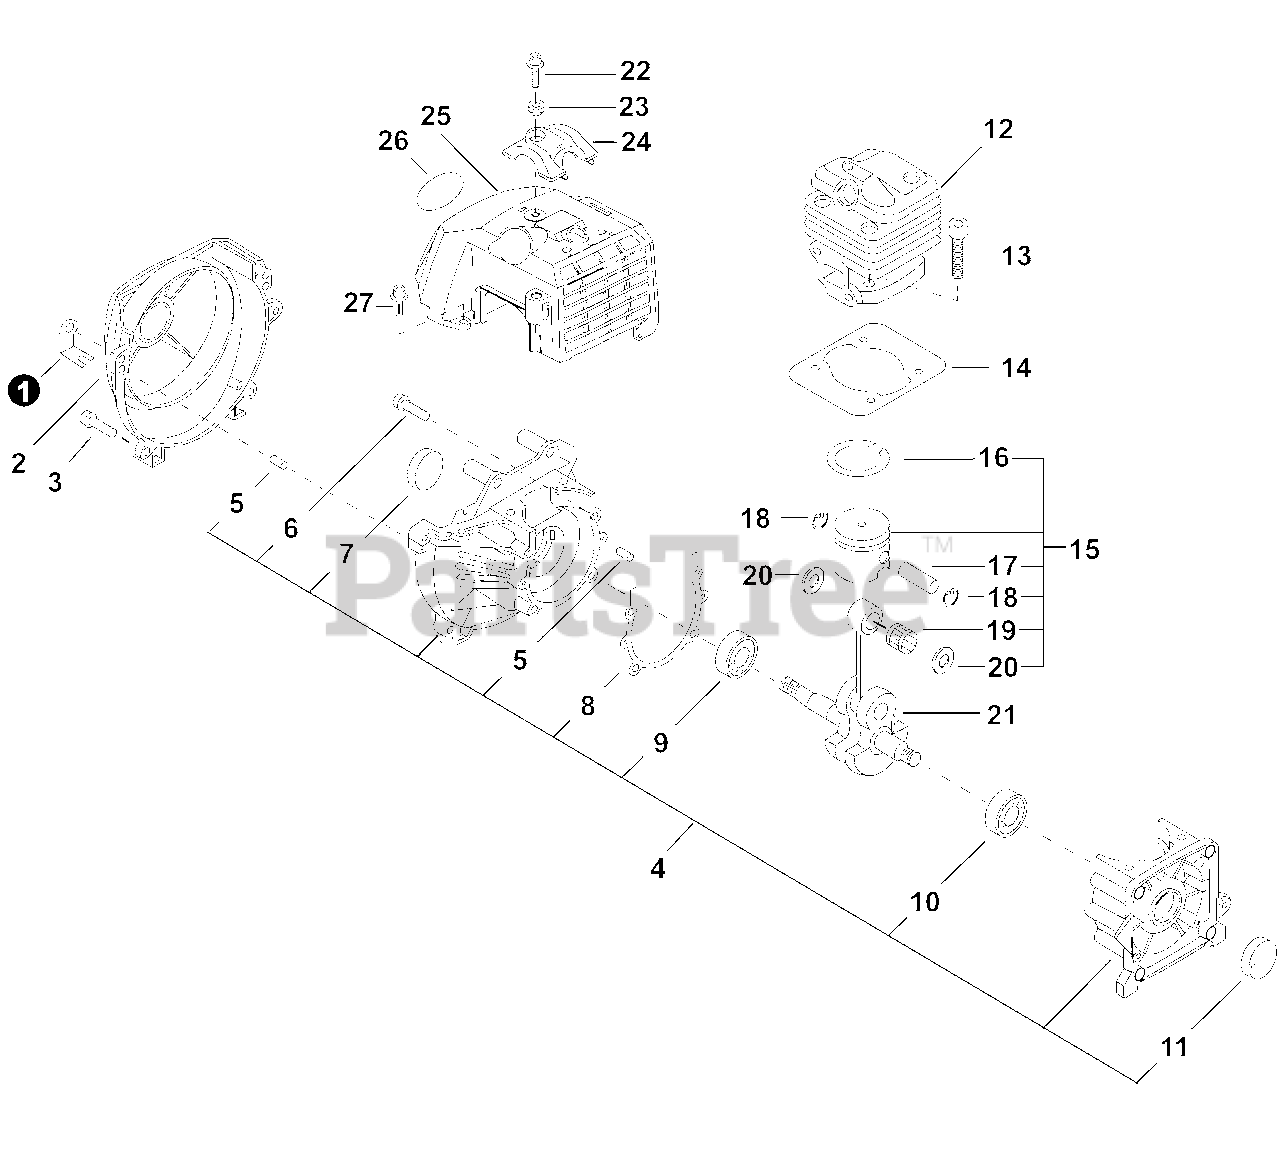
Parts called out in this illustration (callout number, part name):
1	HOLDER, CABLE
2	COVER, FAN
3	BOLT 5×20
4	CRANKCASE KIT
5	PIN, LOCATING 4×8
6	BOLT M5×35
7	SEAL, OIL
8	GASKET, CRANKCASE
9	BEARING, BALL - 6201 C3
10	BEARING, BALL 6202
11	SEAL, OIL 12
12	CYLINDER
13	BOLT 5×20
14	GASKET, CYLINDER
15	PISTON KIT
16	RING, PISTON
17	PIN, PISTON 10
18	RING, SNAP Ø10
19	BEARING, NEEDLE 10
21	CRANKSHAFT ASSY
22	BOLT 5×20
23	COLLAR 5
24	GUARD, TOP
25	COVER, ENGINE
26	LABEL - MODEL B430
27	BOLT 5×12
